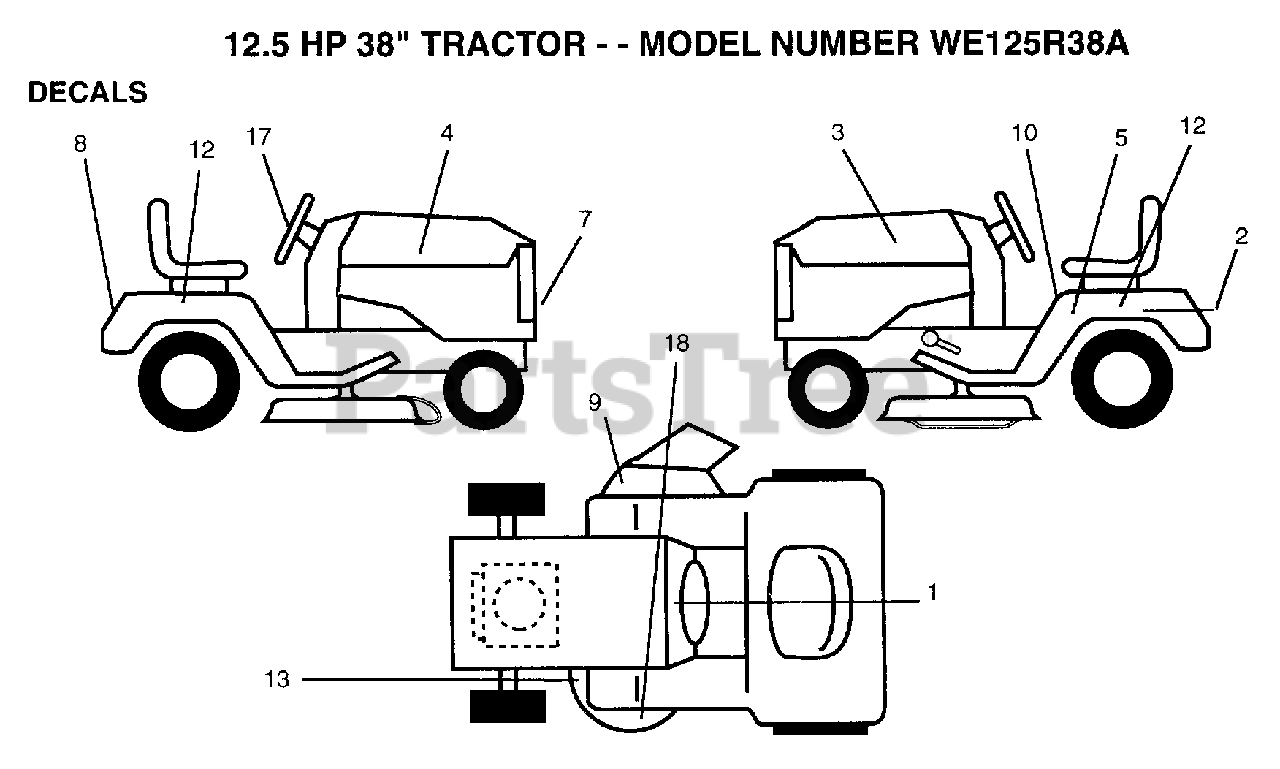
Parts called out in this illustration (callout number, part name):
2	DECAL
3	DECAL.HOOD.LH
4	DECAL.HOOD.RH
5	IND HGT DECK DECA
7	"DECAL,LIGHT BOX"
8	DECAL.FENDER
9	"DECAL, WARNING"
10	DECAL CAUTION
12	DECAL.FEND.QUICKS
13	DECAL
17	DECAL.WHL.STRG.
18	DECAL.MOWER
